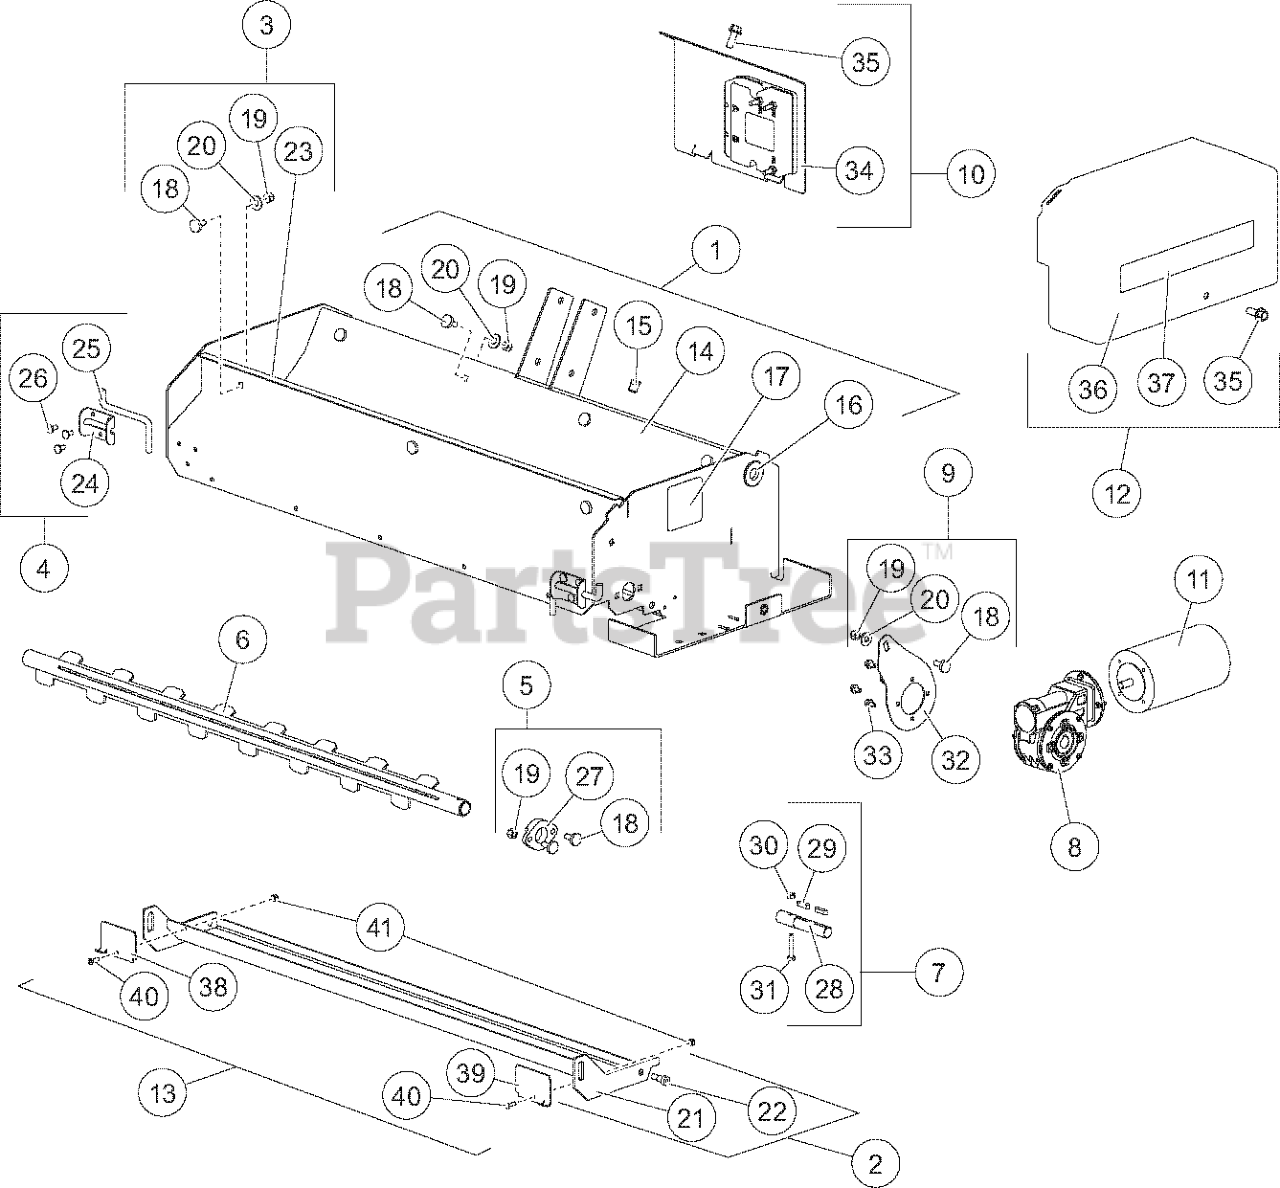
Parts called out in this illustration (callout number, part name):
1	FRAME KIT
2	DROP TROUGH KIT
3	FLAP AGITATOR KIT
4	LOCKING PIN KIT
5	POLY BEARING KIT
6	PADDLE AUGER KIT
7	DRIVE SHAFT KIT
8	GEAR BOX
9	TORQUE ARM KIT
10	ELECTRICAL COVER KIT
11	MOTOR KIT
12	MOTOR COVER KIT
13	SPREADER WIDTH BAFFLE KIT
14	FRAME
15	3/8-16 HEX RIVNUT
16	GROMMET KIT
17	LABEL - WARNING, ROTATING PARTS
18	5/16-18 X 3/4 CARRIAGE BOLT SS
19	5/16-18 HEX LOCKNUT GB
20	5/16 FLAT WASHER TYPE A NARROW
21	TROUGH
22	SHOULDER BOLT
23	FLAP AGITATOR
24	PIN KEEPER
25	LOCKING PIN
26	1/4 RIVET
27	PADDLE BEARING
28	AUGER DRIVE SHAFT
29	KEY
30	1/4-20 HEX LOCKNUT GB
31	1/4-20 X 1-1/2 HEX CAP SCREW SS
32	MOTOR PLATE
34	ELECTRICAL COVER
35	3/8-16 X 1 HEX CAP SCREW SS
36	MOTOR COVER
37	LABEL - WARNING/CAUTION, SPREADERS
38	SHUTTLE PLATE, DS
39	SHUTTLE PLATE, PS
40	#10-32 x 5/8 MACHINE SCREW SS
41	#10-32 HEX LOCKNUTS SS
